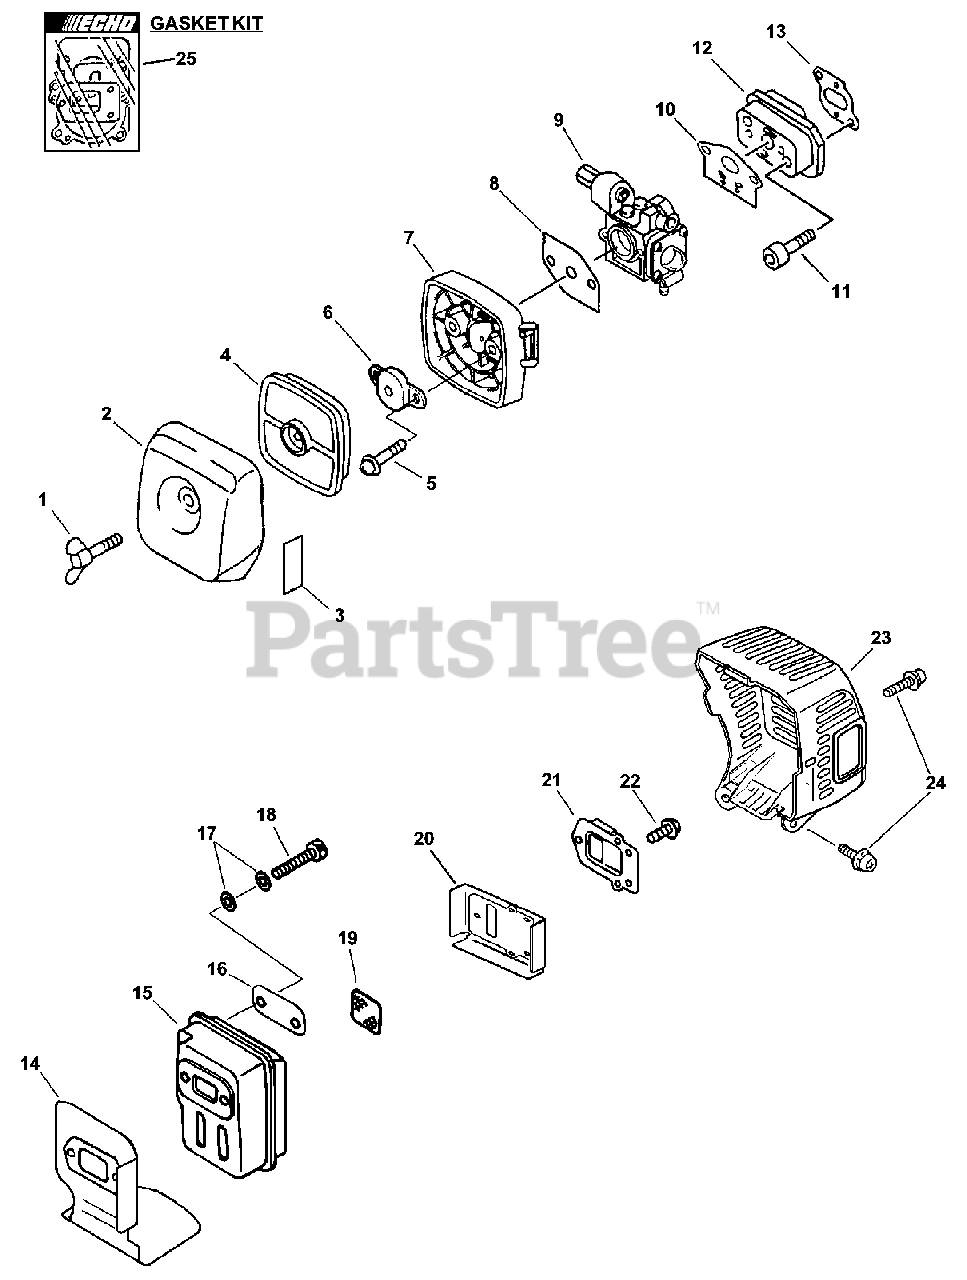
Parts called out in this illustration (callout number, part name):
1	THUMBSCREW
2	COVER, AIR FILTER - GRAY
3	LABEL - CHOKE
4	FILTER, AIR - SINGLE LAYER
5	SCREW - 5X60
6	PLATE, PREVENT
7	CASE, AIR FILTER - GRAY
8	GASKET, INTAKE
9	CARBURETOR RB-K63
10	GASKET, INTAKE
11	SCREW - 5X25
12	INSULATOR, INTAKE
13	GASKET, INTAKE
14	SHIELD, EXHAUST
15	MUFFLER
17	WASHER - CONICAL
18	SCREW - 5X55
19	SCREEN, SPARK ARRESTOR
20	GASKET, EXHAUST
21	GUIDE, EXHAUST
22	SCREW - 4X10
23	COVER, EXHAUST
24	SCREW - 5X12
25	GASKET KIT
